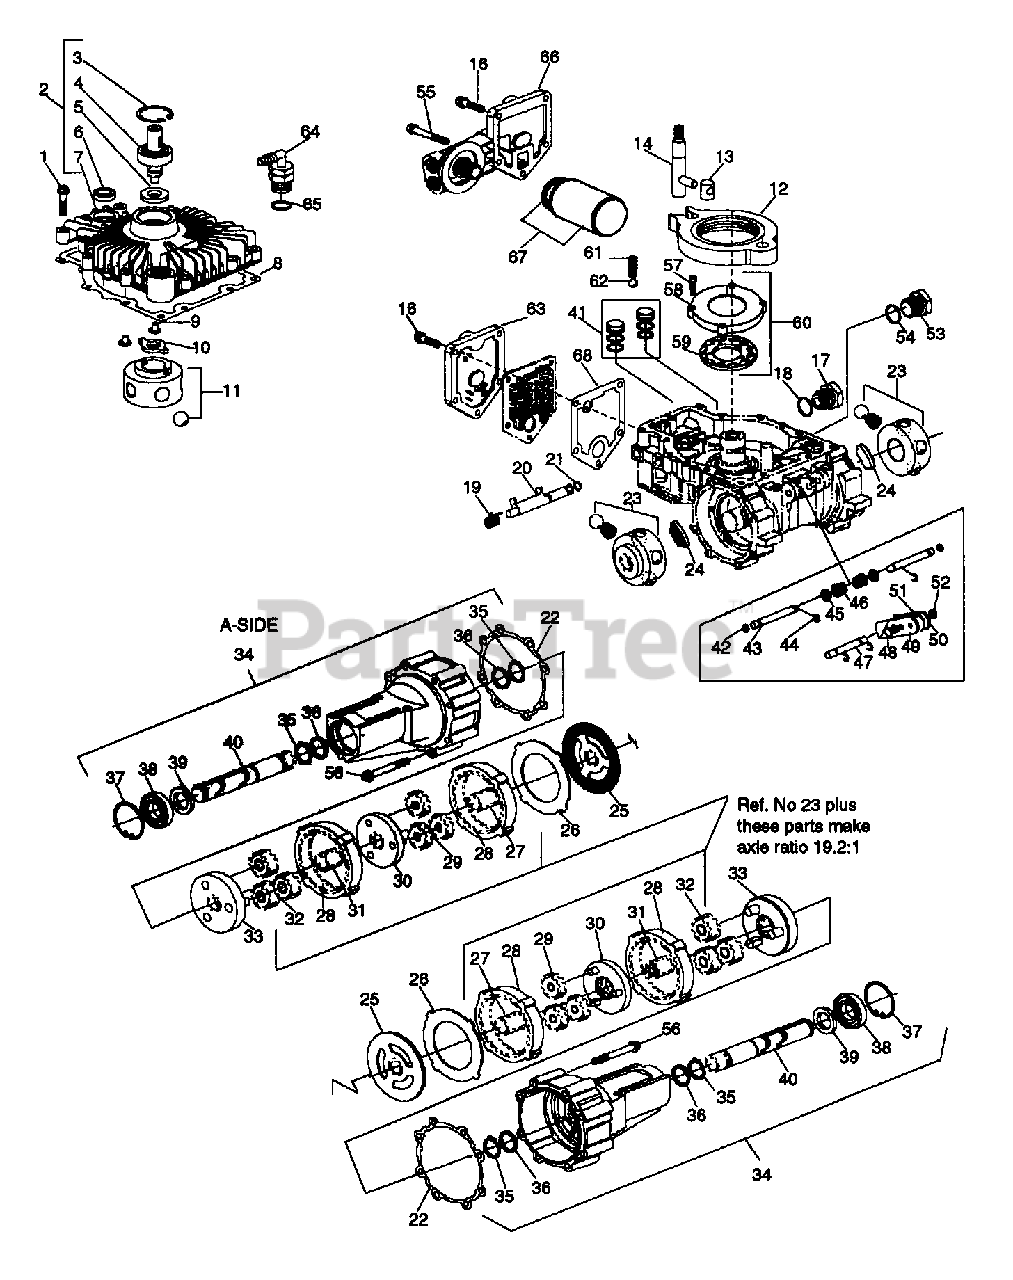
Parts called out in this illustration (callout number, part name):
1	SCREW, 1/4-20 SELF TAP
3	RING RETAINING, INT
4	INPUT SHAFT
5	SEAL, INPUT SHAFT
6	SEAL, CONTROL SHAFT
7	COVER
8	GASKET, COVER
11	PUMP, ROTOR-BALL-PIN S/A
11	PUMP ROTOR/BALL/PIN
12	CAM RING
14	CONTROL SHAFT SUBASSEMBLY
16	SCREW, 1/4 -20 HEX FLANGE
17	DUMP VALVE NUT
19	SPRING, DUMP VALVE
20	BRACKET, DUMP VALVE
21	O-RING, DUMP VALVE BRACKET
22	GASKET, AXLE HOUSING
23	15T MOTOR, ROTOR-BALL S/A
23	MOTOR ROTOR-BALL SUBASSEMBLY
24	PAD, FRICTION
25	PLATE, REACTION
26	PLATE, BACKUP
27	SUN GEAR 15T, FIRST
27	SUN GEAR, 18T, FIRST
28	RING GEAR 57T
28	RING GEAR 54T
29	PLANET GEAR 21T
29	PLANET GEAR 18T
30	PRIMARY CARRIER 15T
31	SUN GEAR 1ST, SECOND
32	PLANET GEAR 21T, SECOND
33	PLANET GEAR 21T, SECOND
34	AXLE HOUSING
35	RETAINING RING, EXT. - B
36	WASHER, THRUST
37	RETAINING RING, INT.
38	BEARING, AXLE SHAFT
39	SEAL, AXLE SHAFT
40	AXLE SHAFT
42	QUAD SEAL
43	PUSH ROD
45	SPRING BASE
46	CONICAL SPRING
47	BRAKE SHAFT
48	BLT-HEX .25-20X.75 PL GR5
49	BRAKE LEVER, RH
50	BRAKE LEVER, LH
52	NUT-LK TOP .250-20 PL
53	.625 RT ANGLE FITTING/O-RING
54	O-RING
55	SCREW 1/4-20 HEX FLANGE
56	SCREW 5/16 HEX FLANGE
57	SCREW, SOCKET, CAP
58	PUMP PLATE
59	GEROTOR
60	PLATE, PUMP & GEROTOR
61	SPRING, RELIEF VALVE
62	BALL, GRADE 200
63	COVER, VALVE
64	ADAPTER, RESERVOIR, 90 DEGREE
65	O-RING
66	FILTER BASE S/A
67	FILTER, OIL (WISEAL)
68	GASKET, FILTER BASE
68	GASKET
